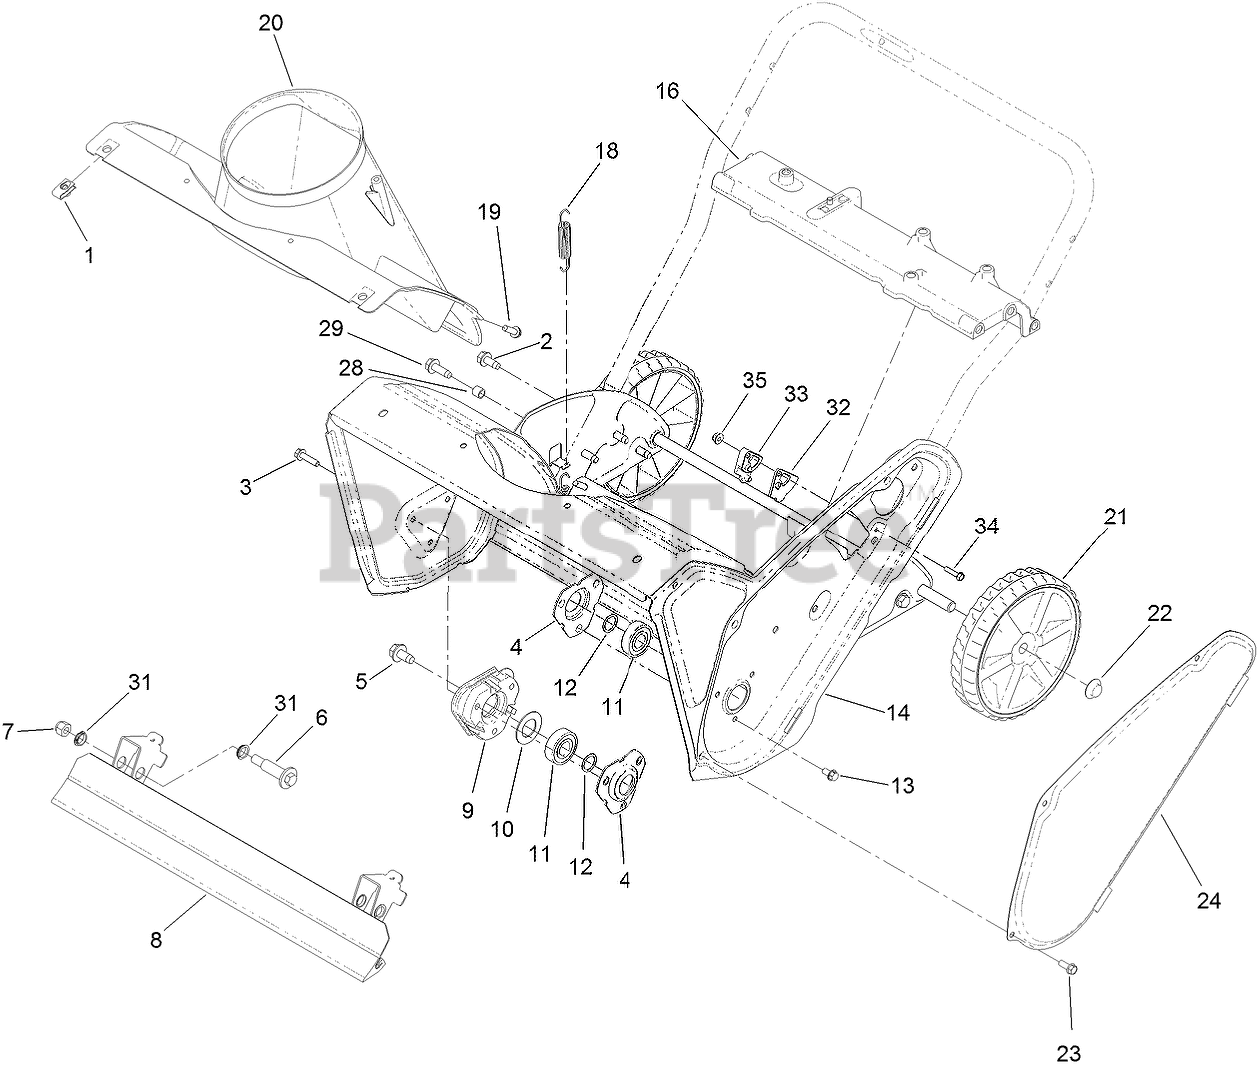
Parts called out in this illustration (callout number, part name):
2	SCREW-THD ROLL, HWH
3	SCREW-HWHTF
4	FLANGE-BEARING
5	SCREW-HWH
6	BOLT-SHOULDER
7	NUT-HEX
8	SCRAPER ASM
9	SPACER-BEARING, RH
10	WASHER-RUBBER
11	BEARING-BALL
12	WASHER-THRUST
13	SCREW-HWH
14	HOUSING-AUGER
16	BRACE-FRAME
18	SPRING-EXTENSION
19	SCREW-PLASTITE, HWH
20	CHUTE-LOWER
21	WHEEL ASM
22	NUT-PUSH
23	SCREW-HWH
24	COVER-BELT
28	SPACER-GROMMET
29	SCREW-THD ROLL, HWH
31	BUSHING-NYLINER
32	CAP-GUIDE, CABLE
33	GUIDE-CABLE
34	SCREW-HWH
35	NUT-HF
